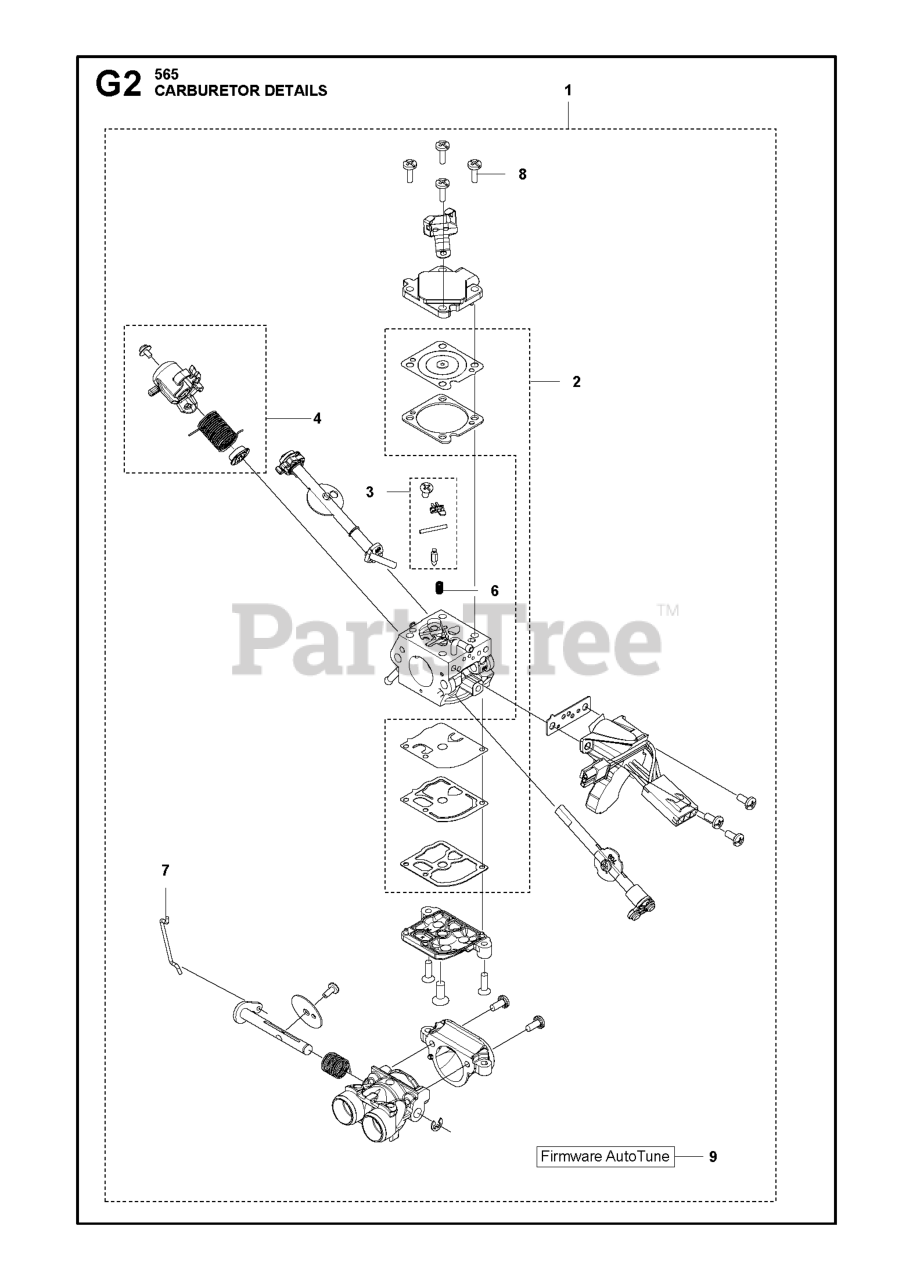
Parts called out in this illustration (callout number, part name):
1	CARBURETTOR KIT 565XP
2	KIT GASKET AND DIAPHRAM
3	CARBURETTOR METERING KIT
4	CARBURETTOR THROTTLE LEVER KIT
